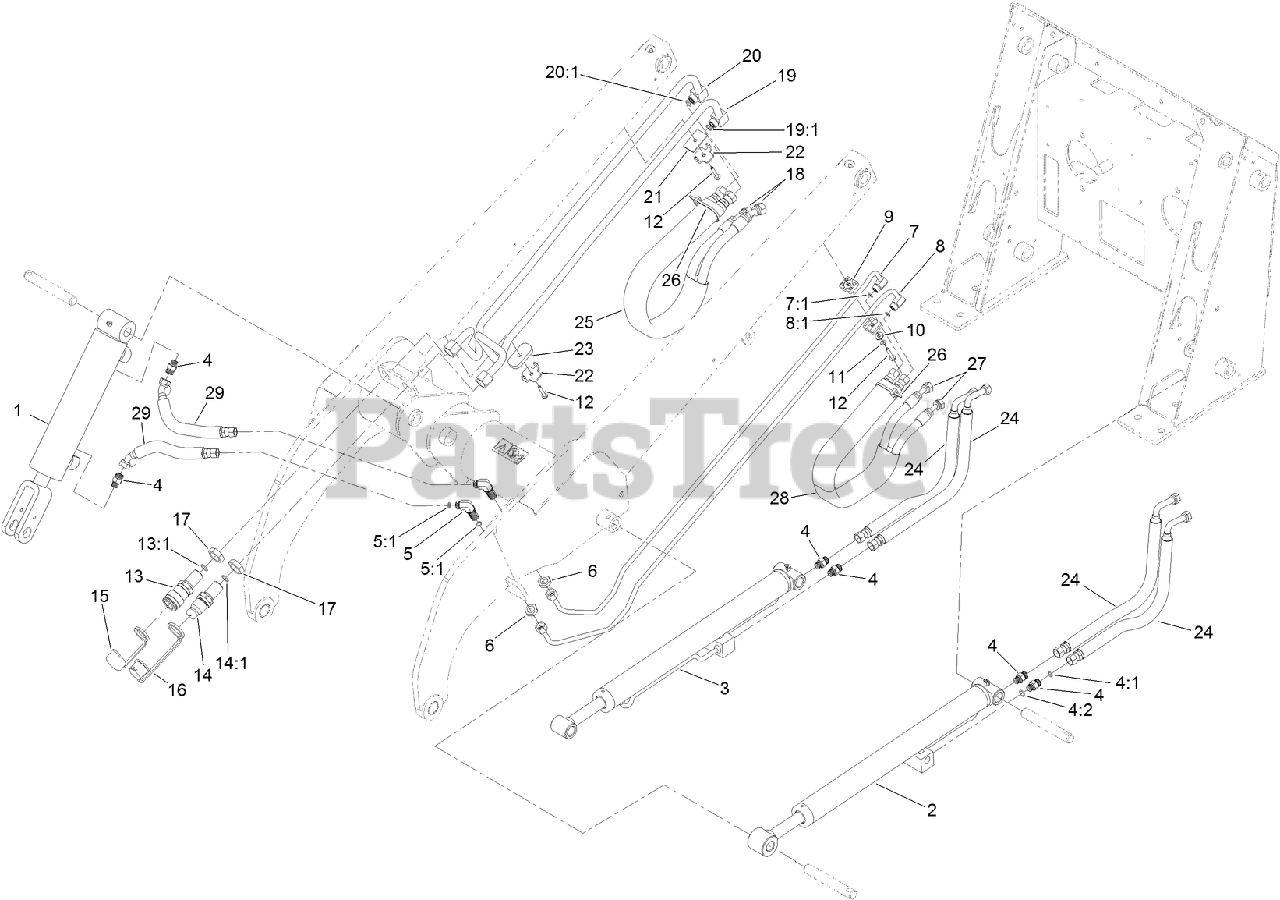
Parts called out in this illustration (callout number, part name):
1	HYD CYL ASM
2	LH HYD CYL ASM
3	RH HYD CYL ASM
4	FITTING-STRAIGHT
4:1	O-RING
4:2	O-RING
5	UNION-BULKHEAD
5:1	O-RING
6	NUT-LOCK
7	HYD TUBE ASM
7:1	O-RING
8	HYD TUBE ASM
8:1	O-RING
9	CLAMP-TUBE
10	WASHER-FLAT
11	WASHER-LOCK
12	SCREW-HWH
13	BULKHEAD COUPLER ASM
13:1	O-RING
14	BULKHEAD NIPPLE ASM
14:1	O-RING
15	CAP-DUST, COUPLER
16	CAP-DUST, NIPPLE
17	NUT-LOCK, BULKHEAD
18	HOSE-HYD
19	HYD TUBE ASM
19:1	O-RING
20	HYD TUBE ASM
20:1	O-RING
21	SPACER-HARDLINE
22	PLATE-CLAMP, TUBE
23	PLATE-HARDLINE
24	HOSE-HYD
25	SLEEVE-PROTECTIVE
26	TIE-CABLE
27	HOSE-HYD
28	SLEEVE-PROTECTIVE
29	HOSE-HYD
